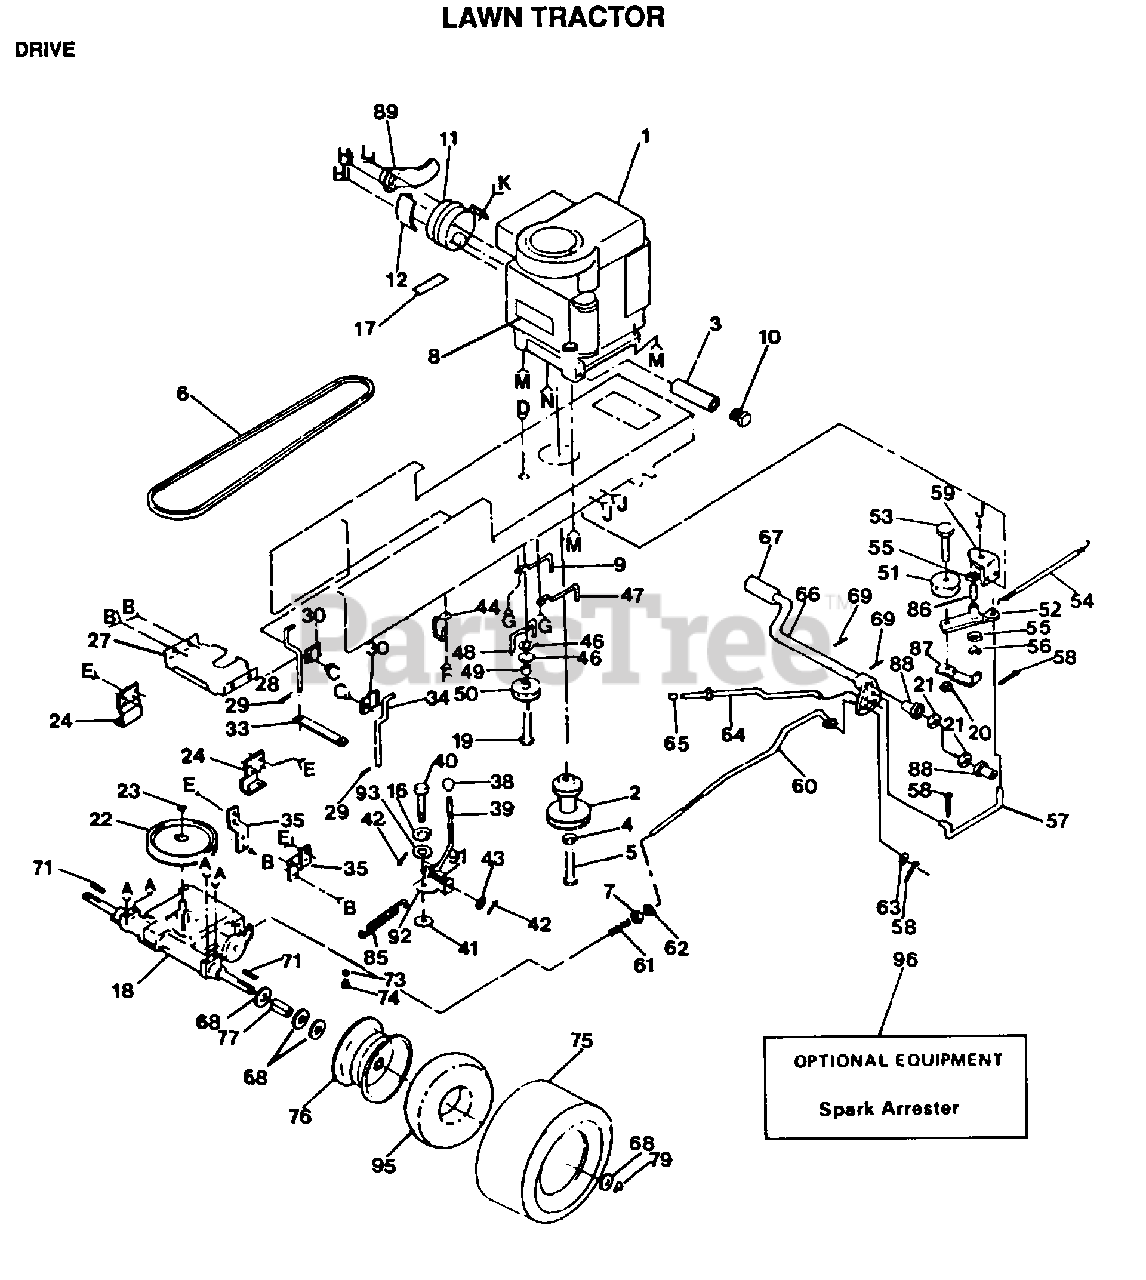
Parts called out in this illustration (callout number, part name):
1	ENGINE BRIGGS AND STRATTON
3	"PIPE, DRAIN OIL"
4	LOCKWASHER
6	BELT-V.90.0.GD.DR
7	NUT
8	DECAL.ENG.271967
9	KEEPER BELT ENGLH
10	"PLUG,DRAIN OIL"
11	MUFFLER LTV
12	SHIELD HEAT LTV
13	"BOLT,HEX"
14	BOLT
15	SCREW
16	LOCKWASHER
19	BOLT
21	WASHER LT
22	PULLEY TRANS
24	BRACKET LT
25	BOLT
26	SCREW
27	BRKT SUPPORT LT
28	KEEPER BELT LH
29	SPRING.RETAINER
30	CLAMP LT
31	BOLT
33	STRAP LOCATOR
34	KEEPER BELTRH
35	STRAP TORQUE
38	CONTROL KNOB LT
39	ROD SHIFTER
41	WASH-SHFT PLT LT
42	PIN COTTER 1/8
43	WASHER
45	SCREW
46	WASHER
47	"KEEPER,BLT ENG LT"
48	BELT KEEPER LT
49	SPACER T
50	PULLEY.IDLER.FLAT
52	ARM IDLER
54	"SPRING, RETURN LT"
55	WASHER LT
56	KLIP RING
57	"LINK, CLUTCH T"
57	RETAIN BELT
58	COTTER PIN
59	BRKT ASM
60	BRAKE ROD LT
61	SPRING ROD LT
62	NUT
63	WASHER
67	PEDAL COVER T
68	WASHER
71	SQUARE KEY
73	VALVE CAP
74	VALVE STEM LT
75	TIRE.TS2.18X8.5
77	SPACER LT
79	E-RING LT
84	BOLT
86	"LY, BEARING"
88	NYLON BEARING
89	DEFLECTOR MUFFLER
91	SPRING LT
92	PLATE SHIFT LT
93	WASHER LT
94	LOCKWASHER
95	TUBE.18X9.5-8
97	WASHER T
